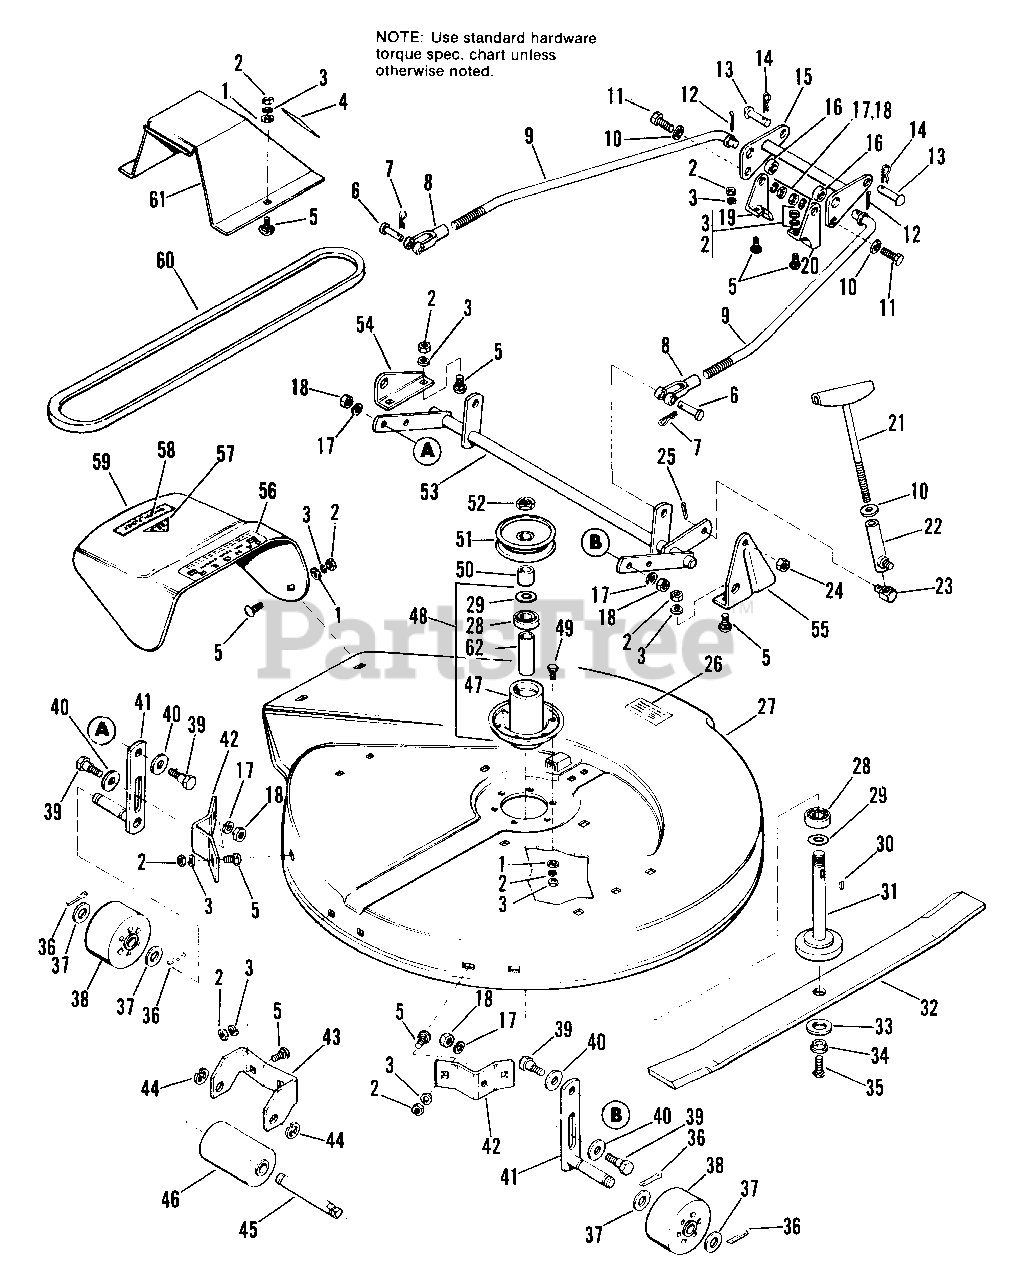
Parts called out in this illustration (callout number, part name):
1	WASHER, Plain, 5/16
2	NUT, Hex, Full, 5/16-18
3	LOCKWASHER, 5/16
5	BOLT, Carriage, 5/16- 18 x 5/8
6	PIN, Yoke
7	PIN, Quick
9	ROD, Adjusting
10	WASHER, Plain, 3/8
11	CAPSCREW, Hex Hd., 3/8-16 x 1-1/2
12	PIN, Cotter, 1/8 x 1
13	PIN
14	CLIP, Hair Pin
15	BELLCRANK ASSY.
17	LOCKWASHER, 3/8
18	NUT, Hex, Full, 3/8-16
19	ANCHOR, Housing, L.H.
20	ANCHOR, Housing, R.H.
21	SCREW ASSY., Adjusting
22	SOCKET ASSY., Crank
24	LOCKNUT, Hex, 3/8-16
25	PIN, Cotter, 3/32 x 5/8
26	TRANSFER, Patent
27	HOUSING, 26"
28	BEARING, Ball
30	KEY, Woodruff, #61
31	ARBOR ASSY.
32	BLADE, 26"
33	WASHER, Belleville
34	WASHER, Shoulder
35	CAPSCREW, Hex Hd., 1/2-20 x 1 L.H. Thd.
36	PIN, Cotter, 3/16 x 1
37	WASHER, Plain, 5/8
38	ROLLER ASSY.
39	BOLT, Shoulder, 3/8-16 X 1.34
40	WASHER, Plain, 7/16
41	SUPPORT ASSY., Roller
42	BRACKET, Roller Support
44	RING, Retaining
45	SHAFT, Center Roller
46	OLLER ASSY.
47	TUBE ASSY., Arbor
48	TUBE ASSY., Arbor W/Bearings
49	CAPSCREW, Hex Hd., 5/16-18 x 3/4
51	PULLEY, Mower
52	LOCKNUT, Jam, 3/4-16
53	ARM ASSY.
54	BRACKET, Pivot, L.H.
55	BRACKET, Pivot, R.H.
56	FILM, Safety
57	DECAL, Safety
58	DECAL, Safety
59	DEFLECTOR
61	COVER, Belt
